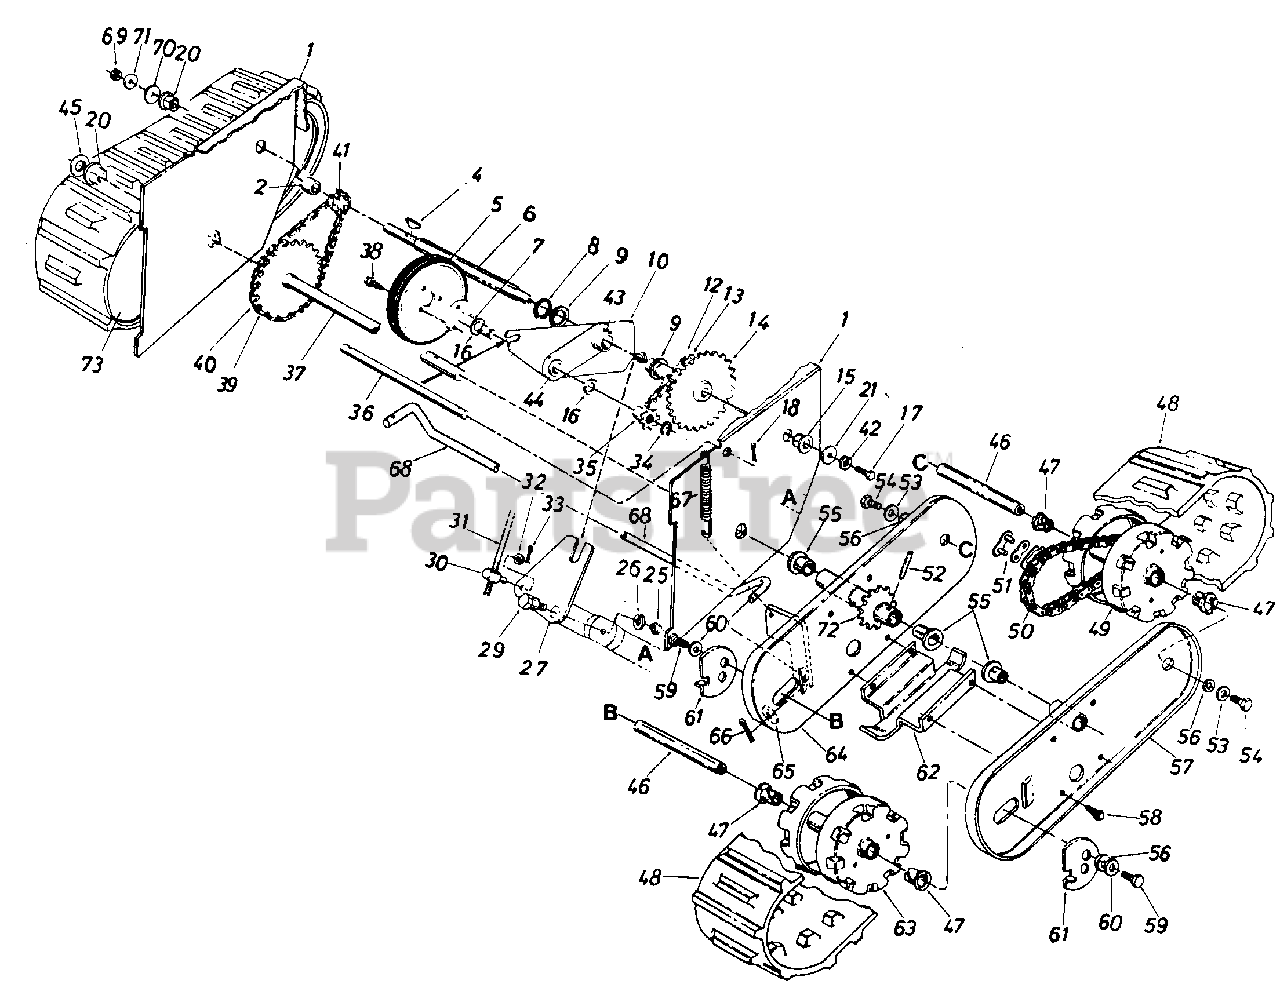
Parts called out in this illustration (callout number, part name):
1	FRAME ASSY
4	KEY-HI-PRO #4-3/32X5/8 DIA-HDN
5	WHEEL ASSY-FRICTION
6	SHAFT-HEX
7	PLATE ASSY-FRICTION WHEEL MTG
8	RING-SNAP FOR 1.00 DIA SHAFT
9	WASHER-FL-1.03 ID X 1.62 X .03 HD
10	BRACKET ASSY-SLIDING
12	#41 CHAIN 12" PITCH X 35 LINKS
13	#41 MASTER LINK 1/2 PITCH TYPEII
14	SPROCKET ASSY-32T
15	BEARING-FLANGE
16	WASHER-FL
17	SCREW-HEX 5/16-18 X .62
18	PIN-COTTER-3/32 DIA X .75
20	BEARING-FLANGE W/FLATS
21	WASHER-FL-.312 X 1.125 X .125
25	NUT-HEX JAM 3/8-18
26	WASHER-LOCK-3/8
27	BRACKET-LINKAGE
29	SCREW-SHLD .625 DIA X .163
30	FERRULE-ADJ
31	ROD-SHIFT
32	WASHER-FL-.344 X .62
33	PIN-COTTER-3/32 DIA X .75
34	RING-C SNAP
35	SPROCKET-7T
37	AXLE ASSY-WHEEL
38	SCREW-HEX WASH SF TAPP
39	#420 CHAIN 1/2 PITCH X 39 LINKS
40	#420 MASTER LINK 1/2 PITCH TYPE II
41	SPROCKET-CENTER #41-8T
42	WASHER-LOCK-5/16
43	BEARING
44	BEARING-FLANGE .630 ID
45	WASHER-FL-.760ID X 1.49OD X .06HDN
46	SHAFT-WHEEL
47	BEARING-FLANGE
48	TRACK-SNOWTHROWER
49	WHEEL ASSY-DRIVE
50	#420 CHAIN 1/2 PITCH X 37 LINKS
51	#420 MASTER LINK 1/2 PITCH TYPE II
52	PIN-SPRING SPIRAL 1/4X1.5 HEAVY DT
53	WASHER-BELL .337 X .867 X .057
54	SCREW-HEX 5/16-24 X .62
55	BEARING-FLANGE
56	WASHER-FL
57	PLATE ASSY-OUTER-LH
58	SCREW-HEX WASH SF TAPP
59	SCREW-HEX 5/16-24 X .62
60	WASHER-BELL .337 X .867 X .057
61	ADJUSTER-TRACK
62	SHOE-SKID
63	IDLER ASSY-WHEEL
64	PLATE ASSY-INNER-LH
65	WASHER-FL-.385 ID X .87 OD X .06
66	PIN-COTTER-1/8 DIA X .75
67	SPRING-EXTENSION
68	ROD-CONNECTING
69	NUT-HEX INS L-1/2-20
70	WASHER-FL-.546 X 1.28 X .090
71	WASHER-BELL .505 ID X 1.00 OD
72	SPROCKET ASSY-17T
73	PLATE ASSY-INNER-RH
